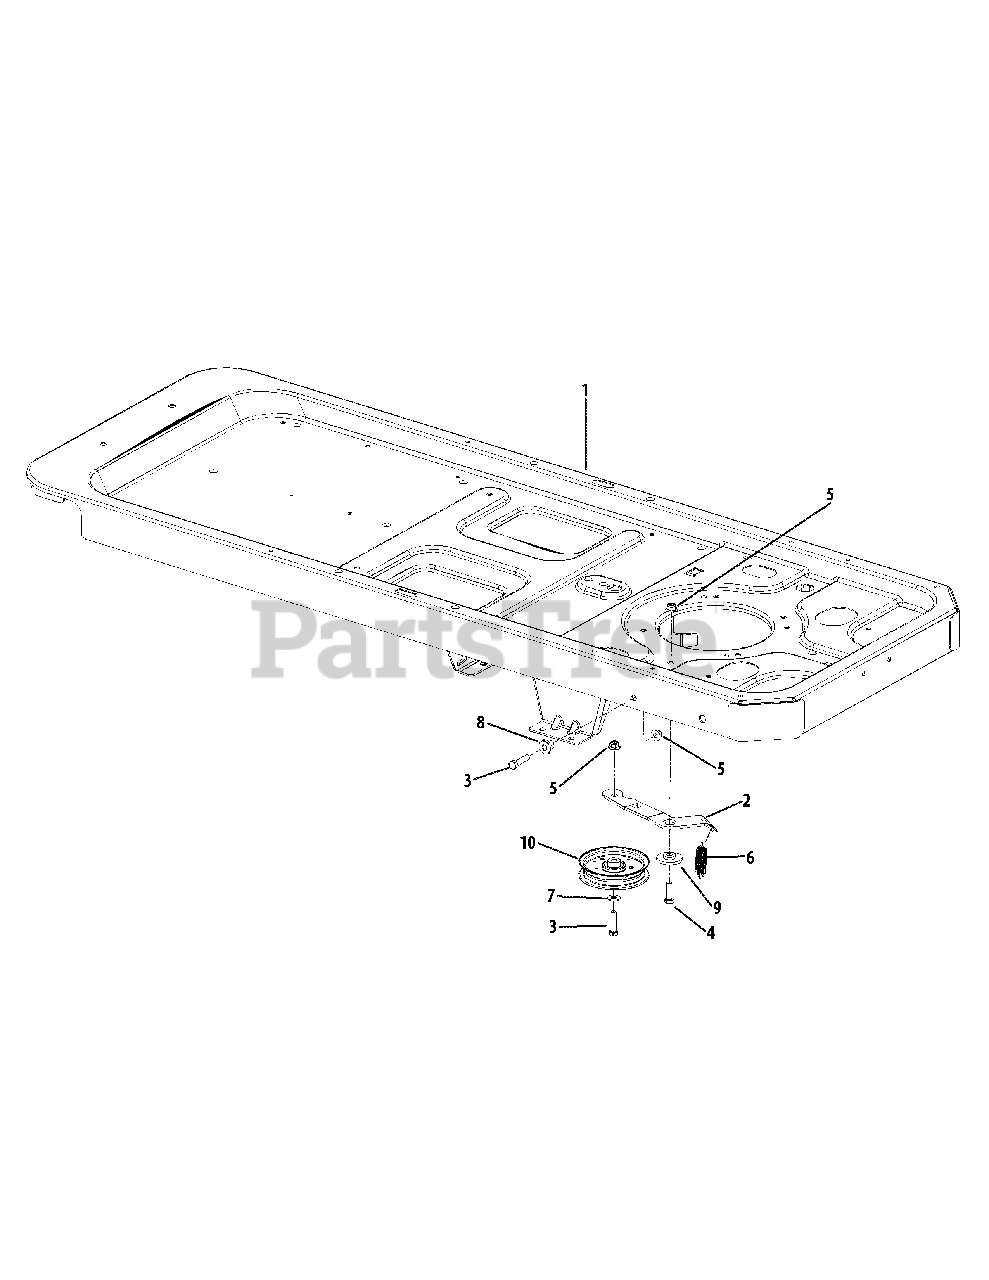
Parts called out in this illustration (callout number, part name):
1	Frame Assembly
2	Drive Idler Arm
3	Hex Screw, 3/8-16 x 1.5
4	Hex Screw, 3/8-16 x 1.25
5	Flange Nut, 3/8-16
6	Extension Spring, .75 x 5.06
7	Flat Washer, .408 x .875 x .059
8	Shoulder Spacer, .39 x 1.0 x .7
9	Shoulder Spacer, .884 x .19
10	Idler Pulley, 4.25 Dia.
